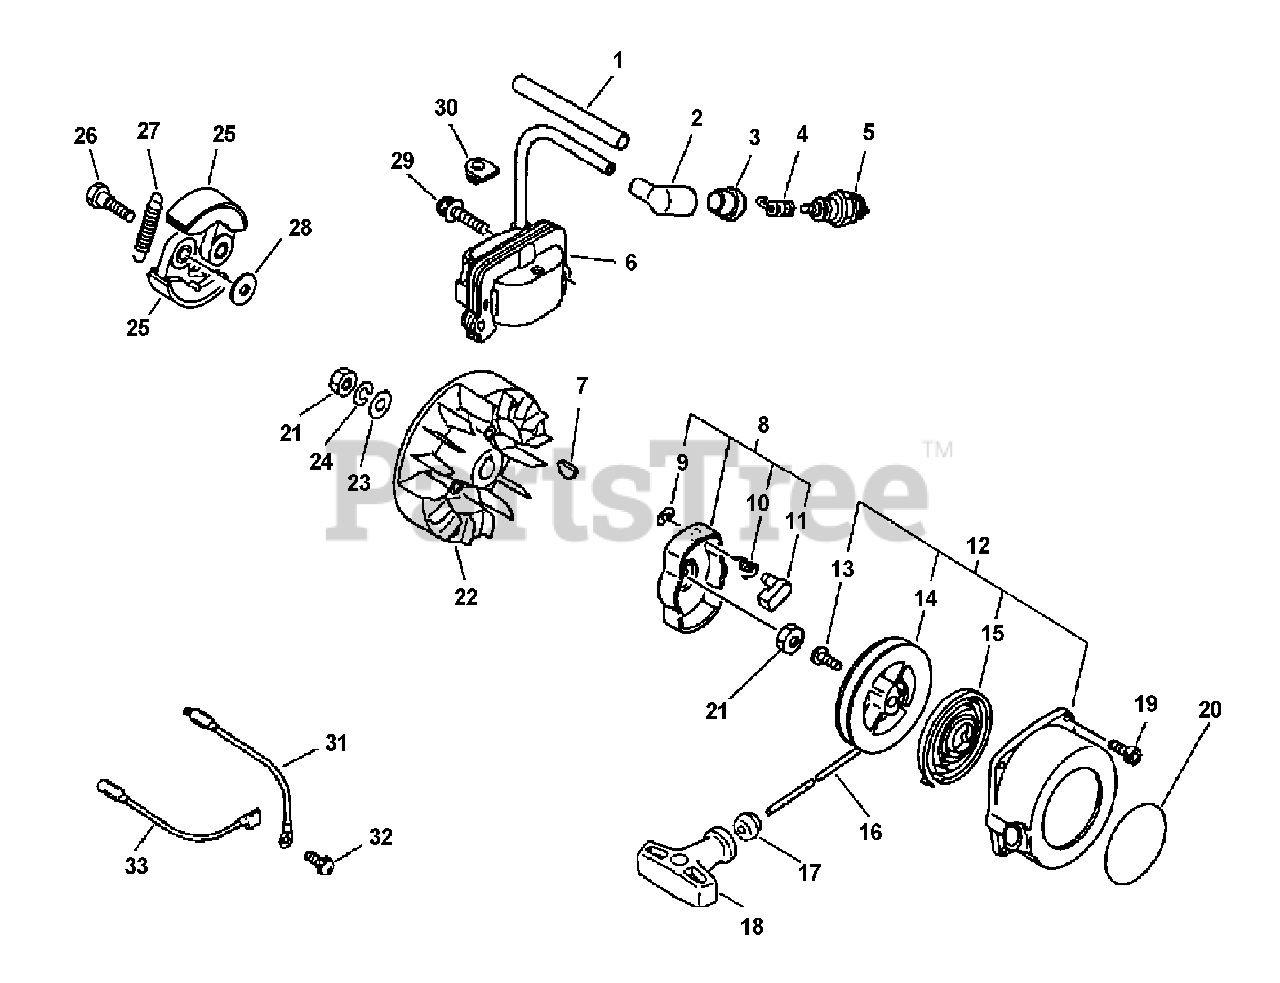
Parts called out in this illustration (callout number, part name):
1	TUBE, PROTECTIVE 6×7×110
2	CAP, SPARK PLUG
3	SEAL, SPARK PLUG
4	TERMINAL, SPARK PLUG
5	SPARK PLUG - BPM7A
5	SPARK PLUG - BPMR7A
6	COIL, IGNITION
7	KEY, WOODRUFF
8	PAWL ASSY, STARTER
9	E-RING 4
10	SPRING, RETURN
11	PAWL, STARTER
12	STARTER ASSY
14	REEL, ROPE
15	SPRING, RECOIL
16	ROPE, STARTER
17	GUIDE, ROPE
18	GRIP, STARTER
19	BOLT 4×14
20	LABEL, ECHO
21	NUT 8×1.25
22	FLYWHEEL
23	WASHER 8.5×16×1.2
24	WASHER, SPRING 8
25	SHOE, CLUTCH
26	BOLT, CLUTCH M6
27	SPRING, CLUTCH
28	WASHER 6.2×19×1.0
29	BOLT 5×20
31	LEAD - GROUND
32	SCREW 5×10
33	LEAD 170 MM
